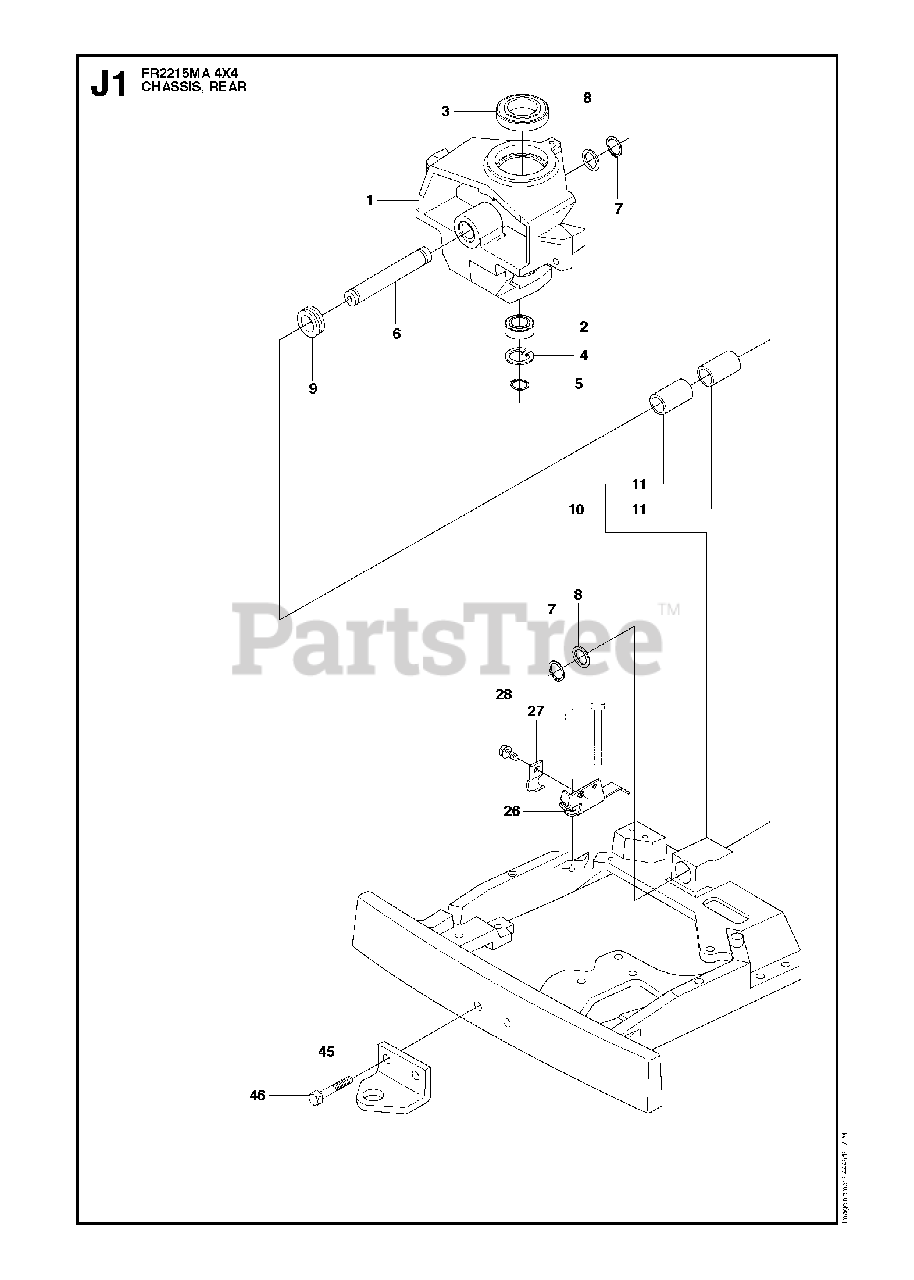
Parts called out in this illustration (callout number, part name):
2	BALL BEARING 6005-2RS
3	BALL BEARING 6010 2RS1
4	CIRCLIP SGH 47
5	RETAINING RING SGA 25
7	RETAINING RING SGA 25
11	BUSHING
45	DRAW RING
46	SCREW M10X25
